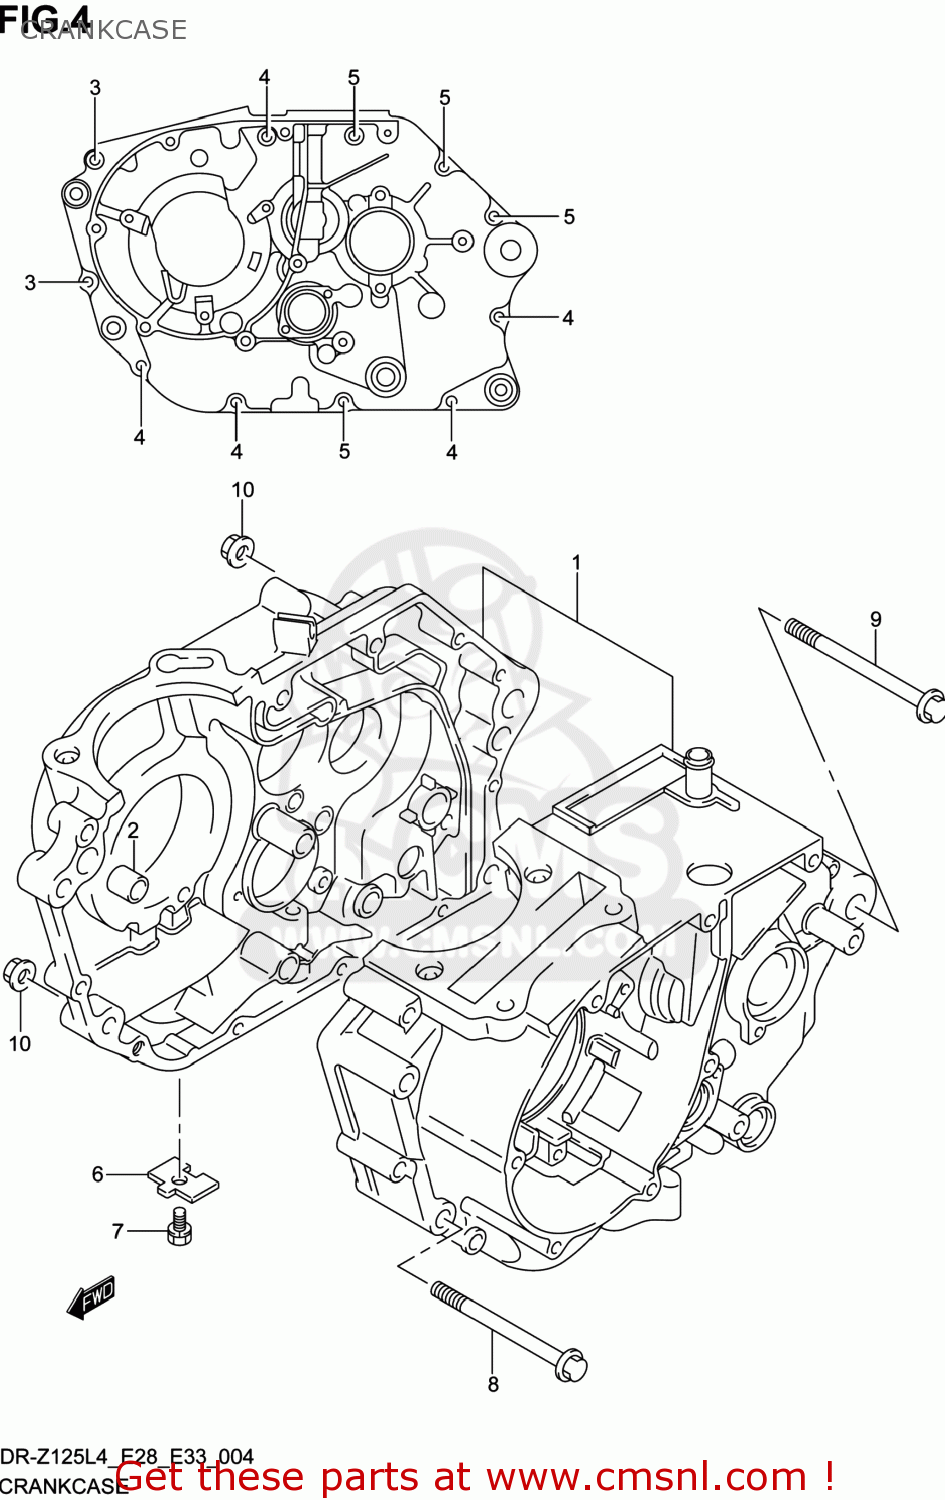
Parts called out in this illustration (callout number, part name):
1	CRANKCASE ASSY
2	PIN
3	BOLT
4	BOLT
5	BOLT
6	PLATE,OIL GALLERY PLUG
7	BOLT
8	BOLT(8X80)
9	BOLT(8X88)
10	NUT
